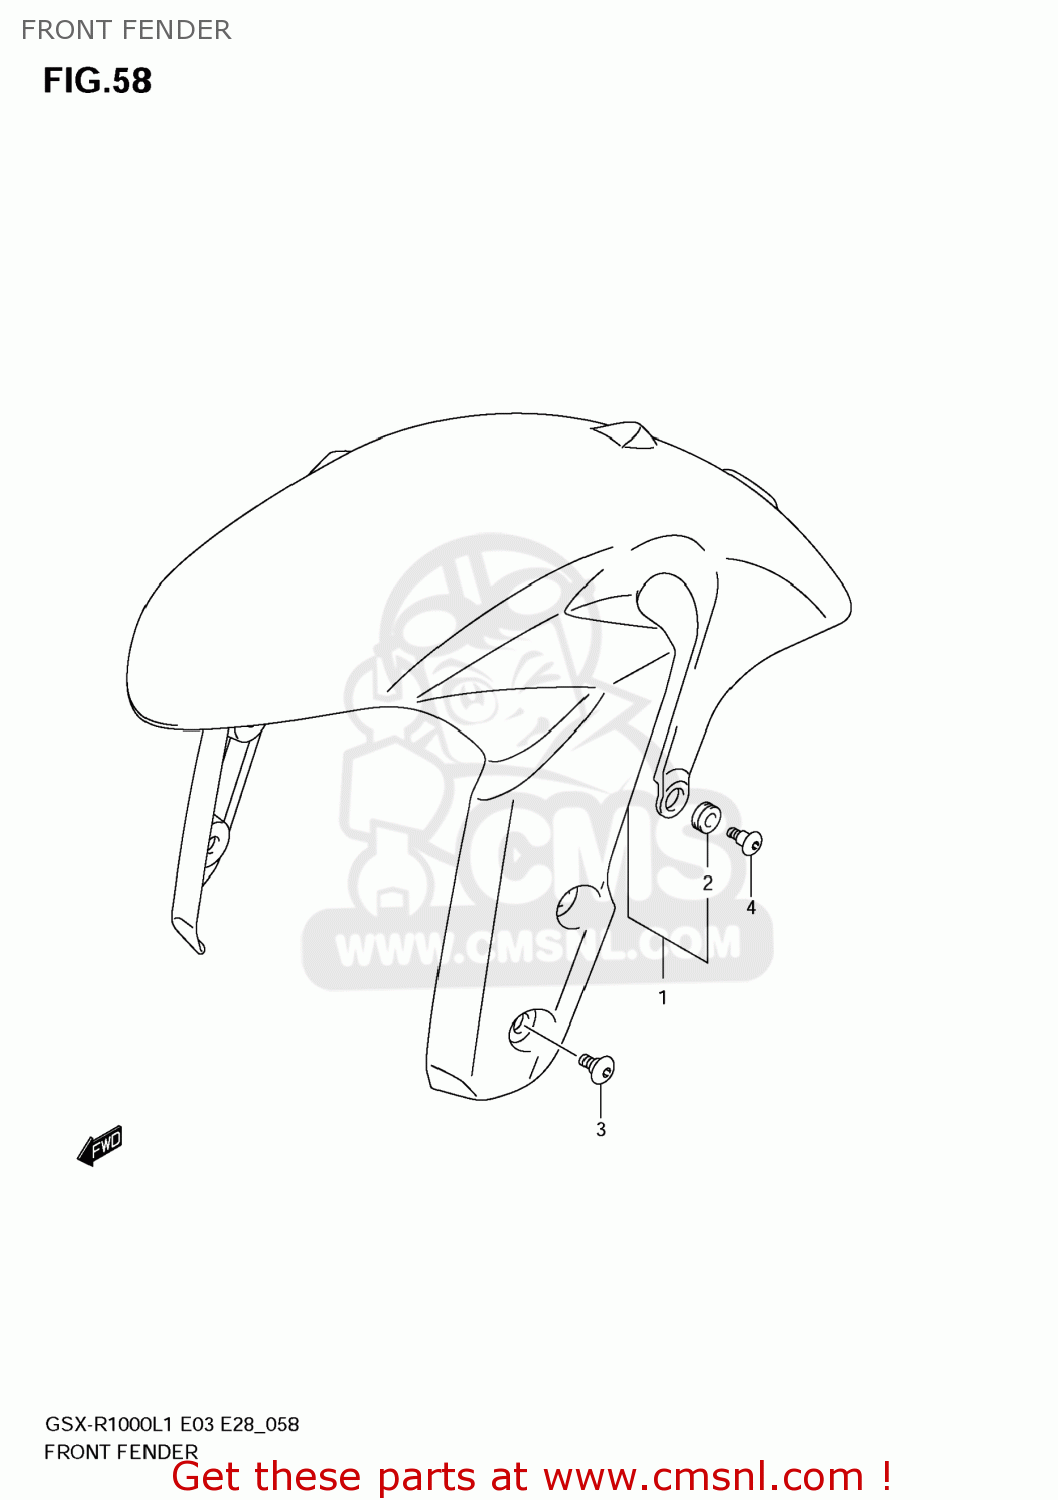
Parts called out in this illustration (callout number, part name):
1	FENDER ASSY,FR(BLACK)
2	CUSHION
3	SCREW(6X16)
4	SCREW(6X16)
